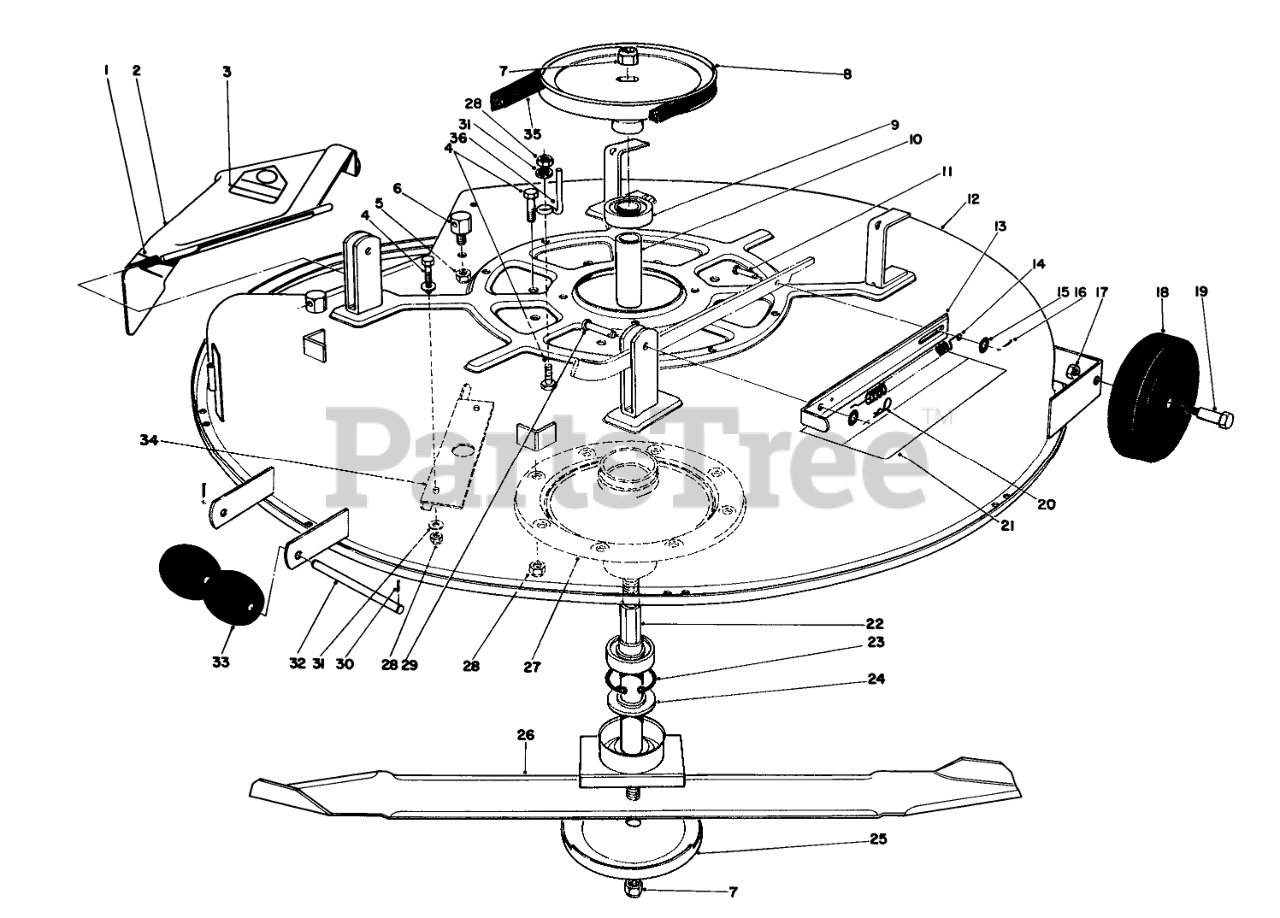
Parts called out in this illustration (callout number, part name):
1	SPRING
2	Deflector Assembly (Incl. Ref. #3)
3	DECAL-DANGER
4	SCREW-HH
5	NUT-LOCK, SIDE
6	POST-PIVOT
8	PULLEY(BLADE DRIVE)
9	BEARING-BALL
10	Spacer-Bearing
11	PIN-CLEVIS
13	DECK SPRING STRAP R
14	DECK TENSION SPRNG O
15	WASHER-FLAT
16	PIN-COTTER
17	NUT-LOCK, NI
18	WHEEL-DECK
19	BOLT-WHEEL
20	PIN-COTTER
21	DECAL-DANGER, THROWN OBJECT
22	SPINDLE SHAFT WA
23	RING-RETAINING
24	SPACER-SPINDLE
25	Cup
26	Blade
27	SPINDLE
28	NUT-LOCK, NI
29	PIN-CLEVIS
30	PIN-COTTER
31	WASHER-PLAIN
32	ROLLER SHAFT
33	ROLLER
34	Baffle Deck
35	V BELT
36	BELT GUIDE
